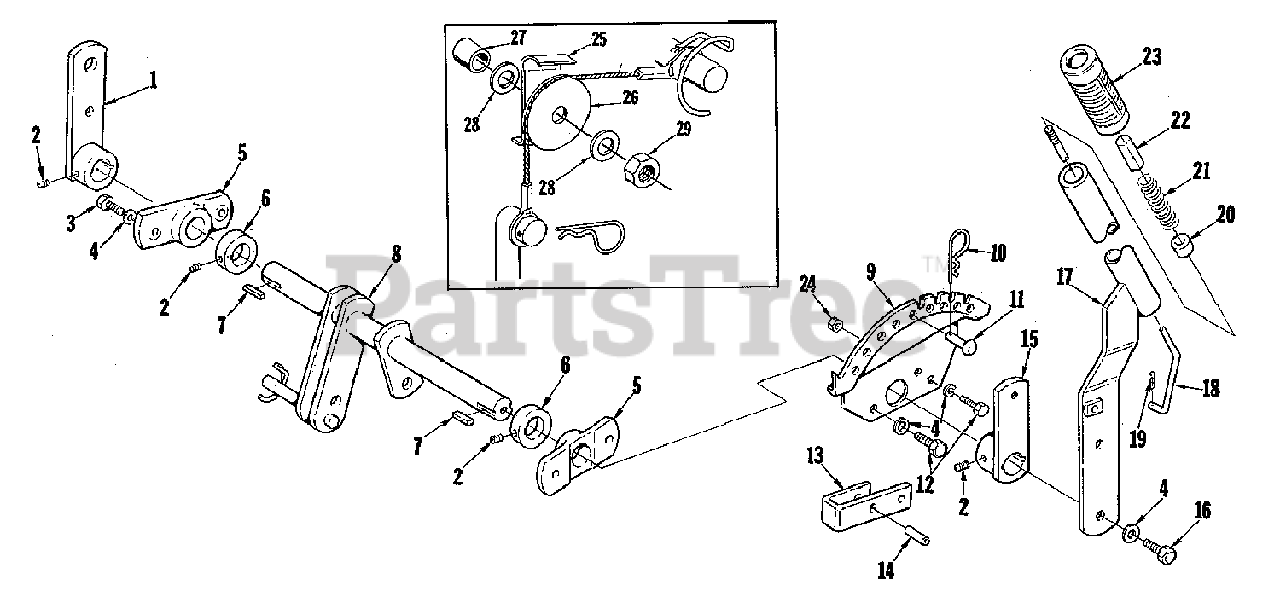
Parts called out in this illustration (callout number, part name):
1	LEVER ASSEMBLY, Front Lift
2	SETSCREW, Hex Socket, 5/6-18 x 5/16
3	SCREW, Hex Head Cap
4	WASHER, Lock
5	BEARING, Lift Lever
7	KEY, Plain Parallel
8	SHAFT ASSEMBLY, Lift
9	QUADRANT, Lift Lever
12	SCREW, Hex Head Cap
13	LATCH, Lift Lever
15	LIFT LEVER ASSEMBLY, Inner Section
16	SCREW, Hex Head Cap, 3/8-16 x 1
17	LEVER ASSEMBLY, Lift
18	ROD, Latch Lift Lever
20	SPACER, Handle, Lift Lever
21	SPRING, Stand
22	BUTTON, Thumb
23	GRIP, Lift Lever
24	NUT, Hex Fin, 3/8-16
25	CLIP, Cable Retaining
27	SPACER, Pulley
28	WASHER, Flat, 13/32
29	NUT, Hex Lock, 3/8-16
